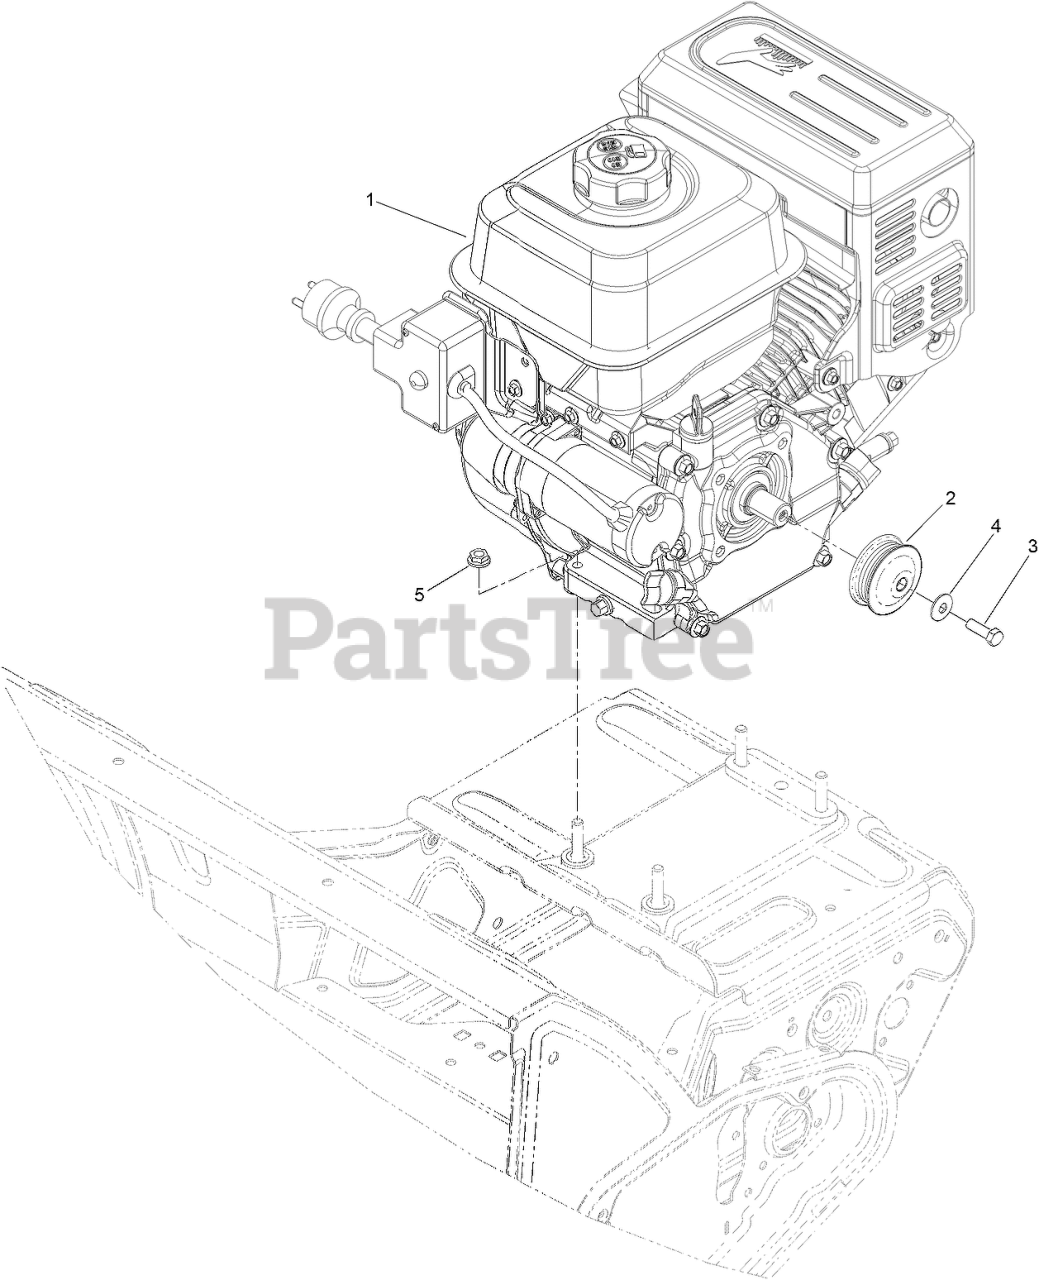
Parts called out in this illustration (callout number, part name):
1	ENGINE-G210FDS-2
2	PULLEY-ENGINE
3	SCREW-HH, LOCK
4	WASHER-BELLEVILLE
5	NUT-HF
